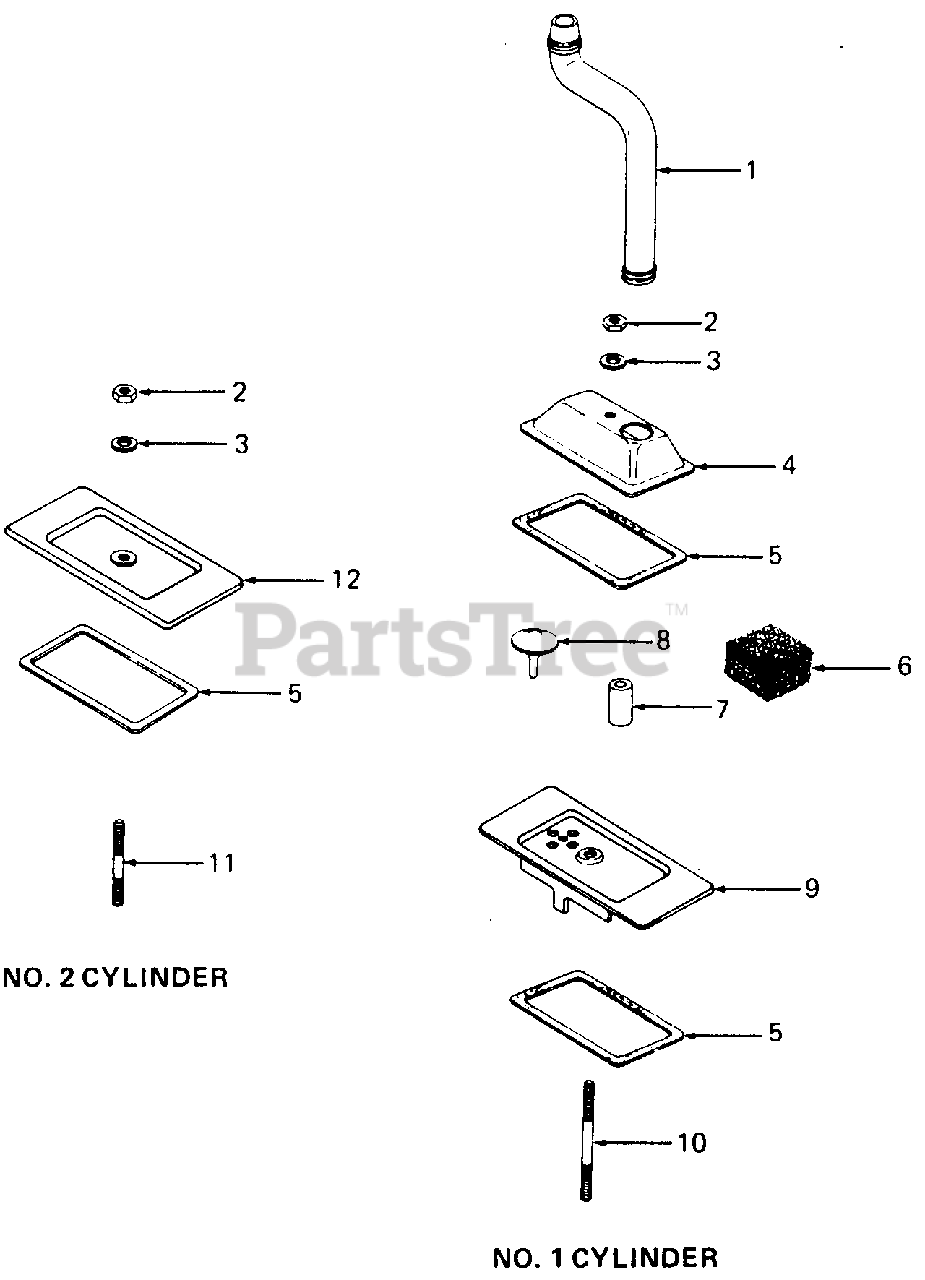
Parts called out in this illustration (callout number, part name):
1	Hose, Breather
2	Nut, Hex, 1/4-20
3	Washer, Plain, 1/4
4	Cover, #1 Upper Cylinder Valve
5	Gasket, Valve Cover
6	Filter, Breather
7	Seal, Breather
8	Valve, Breather
9	Cover, #1 Lower Cylinder Valve
10	Stud, #1 Cylinder Valve Cover, 1/4-20 X 3.25 Lg
11	Stud, #2 Cylinder Valve Cover, 1/4-20 X 2.25 Lg
12	Cover, #2 Cylinder Valve
